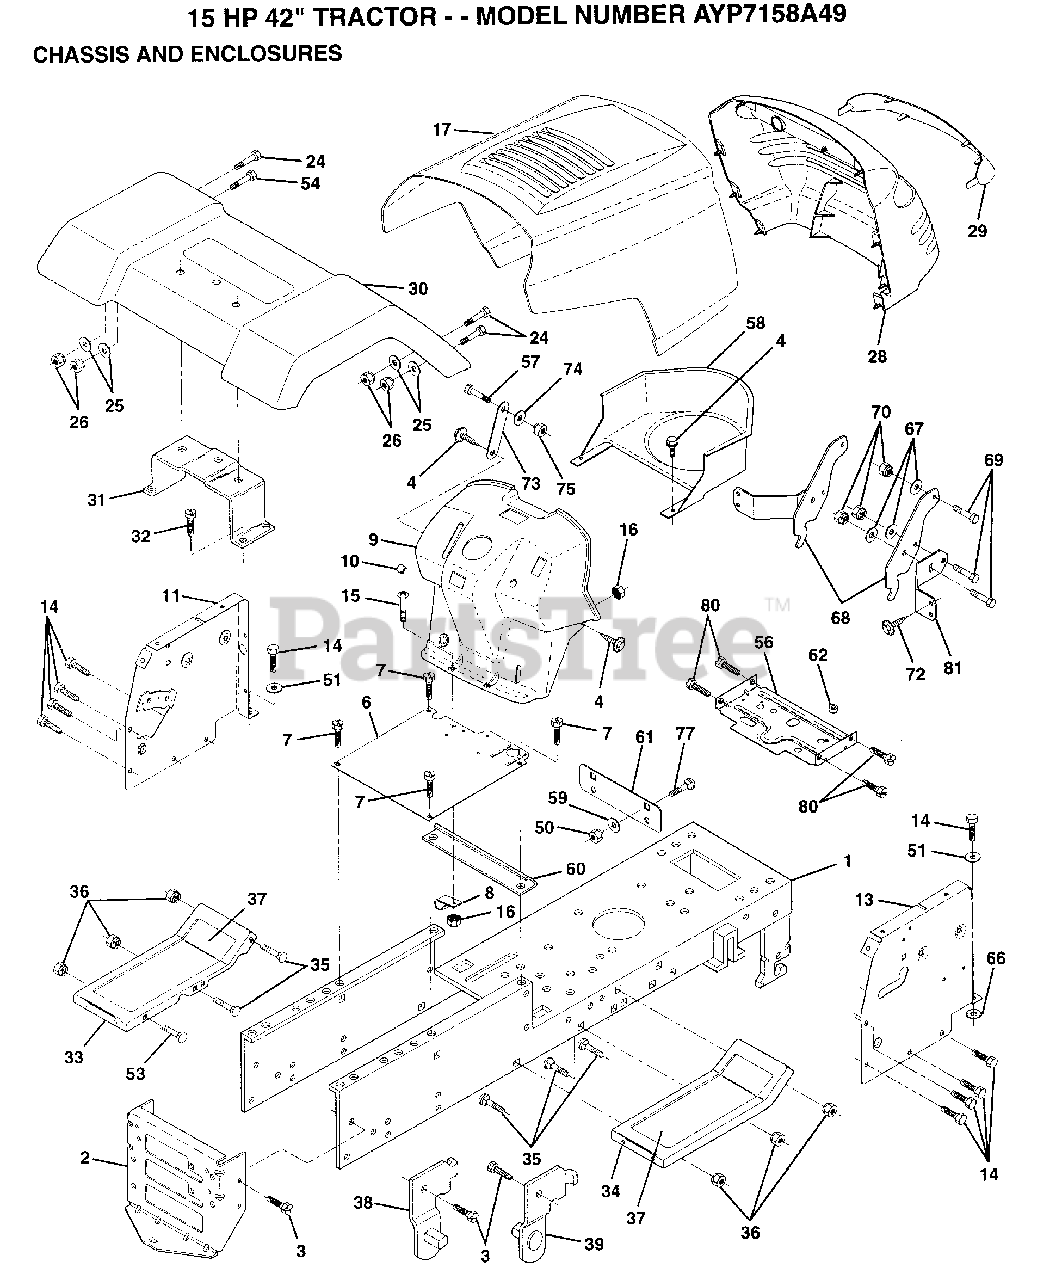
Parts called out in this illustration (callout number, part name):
3	SCREW
4	SCREW HEX CRT
7	SCREW GTV
8	CLIP T
10	PLUG BUTTON T
11	PANEL ASM DASH
14	SCREW LT
16	NUT
25	WASHER
29	HANDLE.LIFT.LH.
31	BRKT FENDER
32	SCREW
35	BOLT
37	FOOTREST PAD
38	BRACKET ASM LH
39	BRACKET ASM RH
50	NUT
51	WASHER
57	SCREW
58	DUCT AIR 12-15H
59	WASHER
60	SPACER FENDER LT
61	PLATE EXTEN FEND
66	LOCKWASHER
67	WASHER
68	HING PICK-OFF HD
69	BOLT LT
73	BRACE SUPT DASH
74	WASHER
75	NUT
77	BOLT D
81	BRACKET GRILLE
